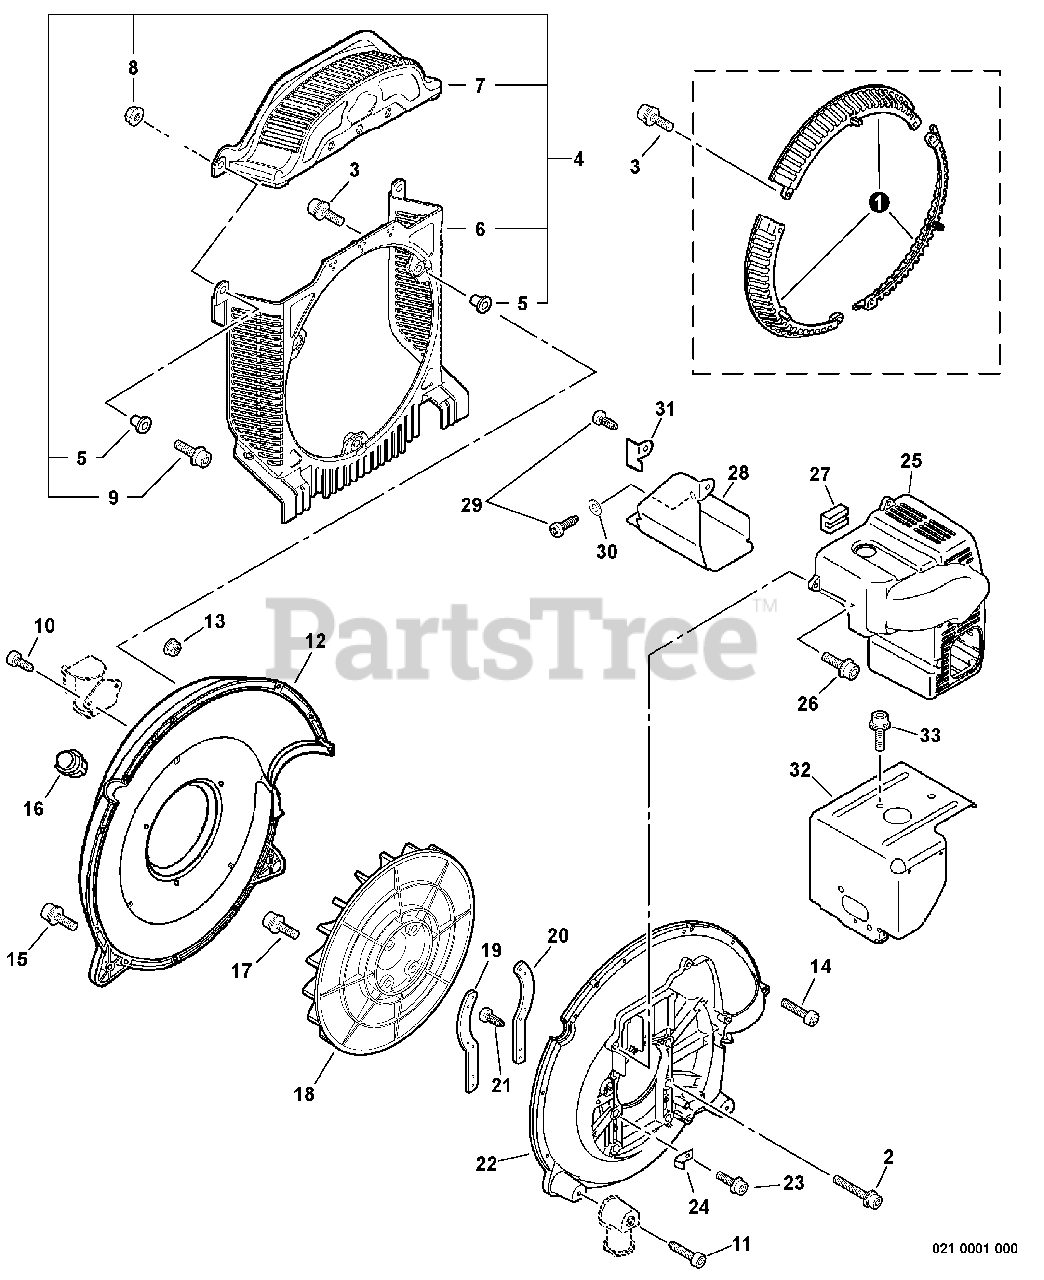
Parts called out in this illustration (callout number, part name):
1	GUARD, DEBRIS
2	SCREW 6×35
3	SCREW TAPPING 5×20
4	GUARD KIT, DEBRIS
6	SHIELD, DEBRIS - LOWER
7	SHIELD, DEBRIS - UPPER
8	NUT, LOCK M5
9	BOLT 5×20
10	SCREW TAPPING 5×16
11	SCREW TAPPING 5×16
12	COVER, FAN - INNER
13	NUT, FLANGE M5
14	BOLT 5×60
15	SCREW TAPPING 5×20
16	PLUG, FAN CASE
17	BOLT 5×30
18	FAN, BLOWER
19	PLATE, ENGINE
20	PLATE, ENGINE
21	SCREW 5×14
22	COVER, FAN - OUTER
23	SCREW TAPPING 5×16
25	COVER, ENGINE
26	SCREW TAPPING 5×20
27	CUSHION
28	INSULATOR, MUFFLER
29	SCREW 5×10
30	WASHER 5.5×12×0.8
31	PLATE, ANGLE
32	COVER, CYLINDER
33	BOLT 5×8
